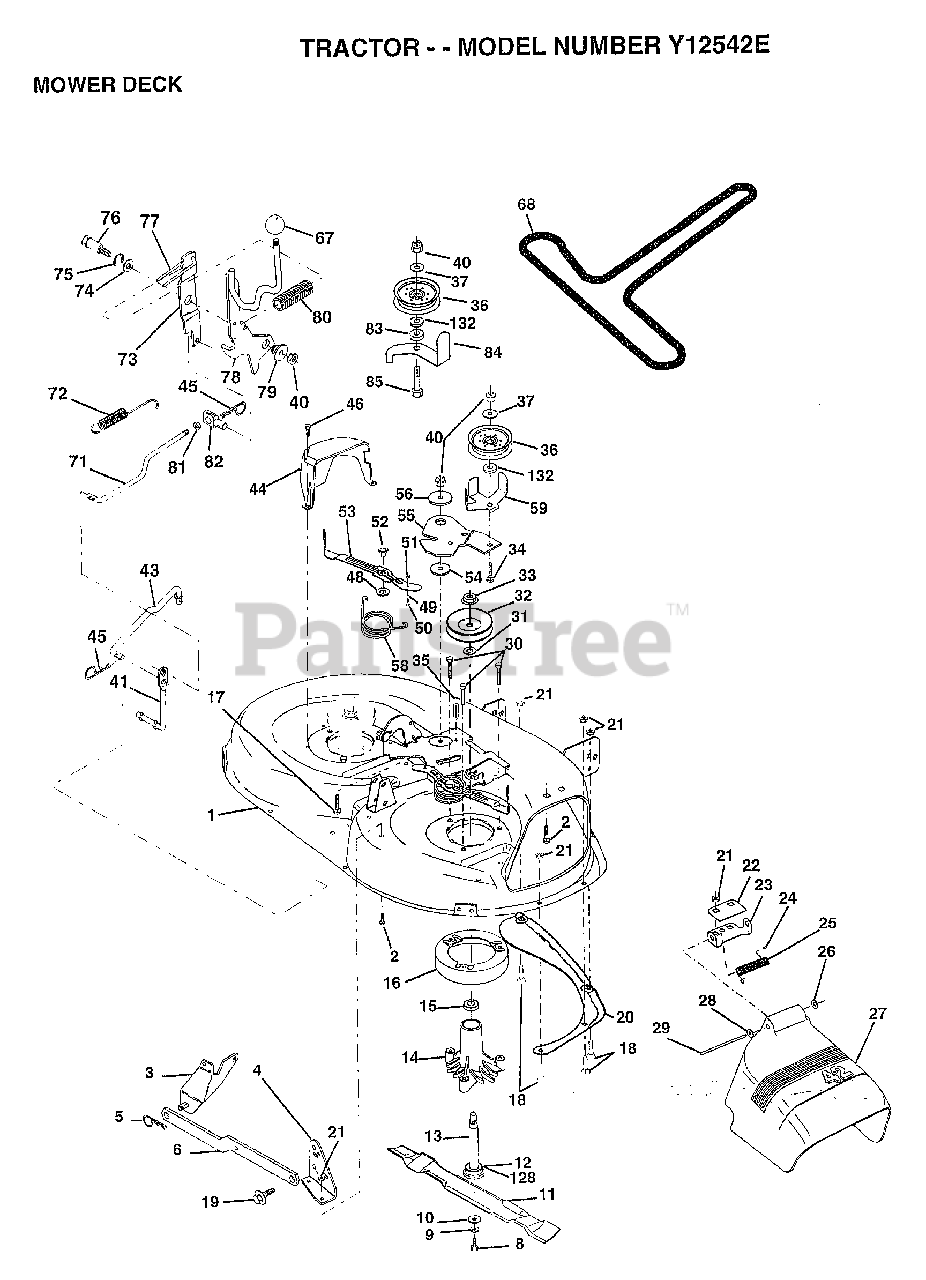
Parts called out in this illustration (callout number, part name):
1	DECK.WELD.42.
2	BOLT
3	BRKT ASM SWAY BAR
4	BRKT DECK SW BAR
8	BLADE BOLT
10	WASHER.HARD.BLADE
11	"BLADE.42"" HIPERF"
12	BEARING.BALL
14	HSG ASM MANDREL
15	BEARING
16	STRIPPER RND MWR
17	BOLT RDHD 3/8-16
18	BOLT
19	BOLT SHD 5/16-18
22	STIFFENER BRKT
23	DEFLECTOR BRKT
24	CAP-SLEEVE LT
25	SPRING TORSION
26	NUT PUSH M
27	DEFLECTOR.SHIELD
28	WASHER
29	HINGE ROD
30	"SCREW-THD ROLL,WA"
31	WASHER
32	PULLEY.MANDREL.42
34	BOLT
35	XMAS TREE FASTNER
36	FLAT IDLER PULLEY
37	WASHER
41	PIVOT ROD
43	ROD CLUTCH W/NIBS
44	GUARD MAND LH BLK
45	RETAINER M
46	SCREW.1/4-20X5/8
48	HARD SMALL WASHER
49	ROLLER ASM-CAM
50	SHOULDER BOLT
51	LOCKNUT
52	BOLT.SHLD.5/16-18
54	HARDENED WASHER
55	ARM-IDLER
56	SPACER RETAINER
58	SPRING TORSN BRAK
59	GUARD IDLER TUV
67	KNOB T (1/2-HOLE)
68	BELT.V.T-PATH
71	ROD CLUTCH 38/42
72	RETURN SPRING
73	CLUTCH ARM SECOND
74	WASHER
75	RING
76	SHOULDER BOLT
77	SPRING KEEPER
78	LEVER CLUTCH ASM
79	BUSHING
80	SPRING.CLUTCH.MWR
81	TRUNION ADJ
82	NUT
83	WASHER
84	"KEEPER-BELT,FIXED"
85	BOLT RDHD 3/8-16
92	NUT
128	WASHER.FELT.
132	WASHER GT
